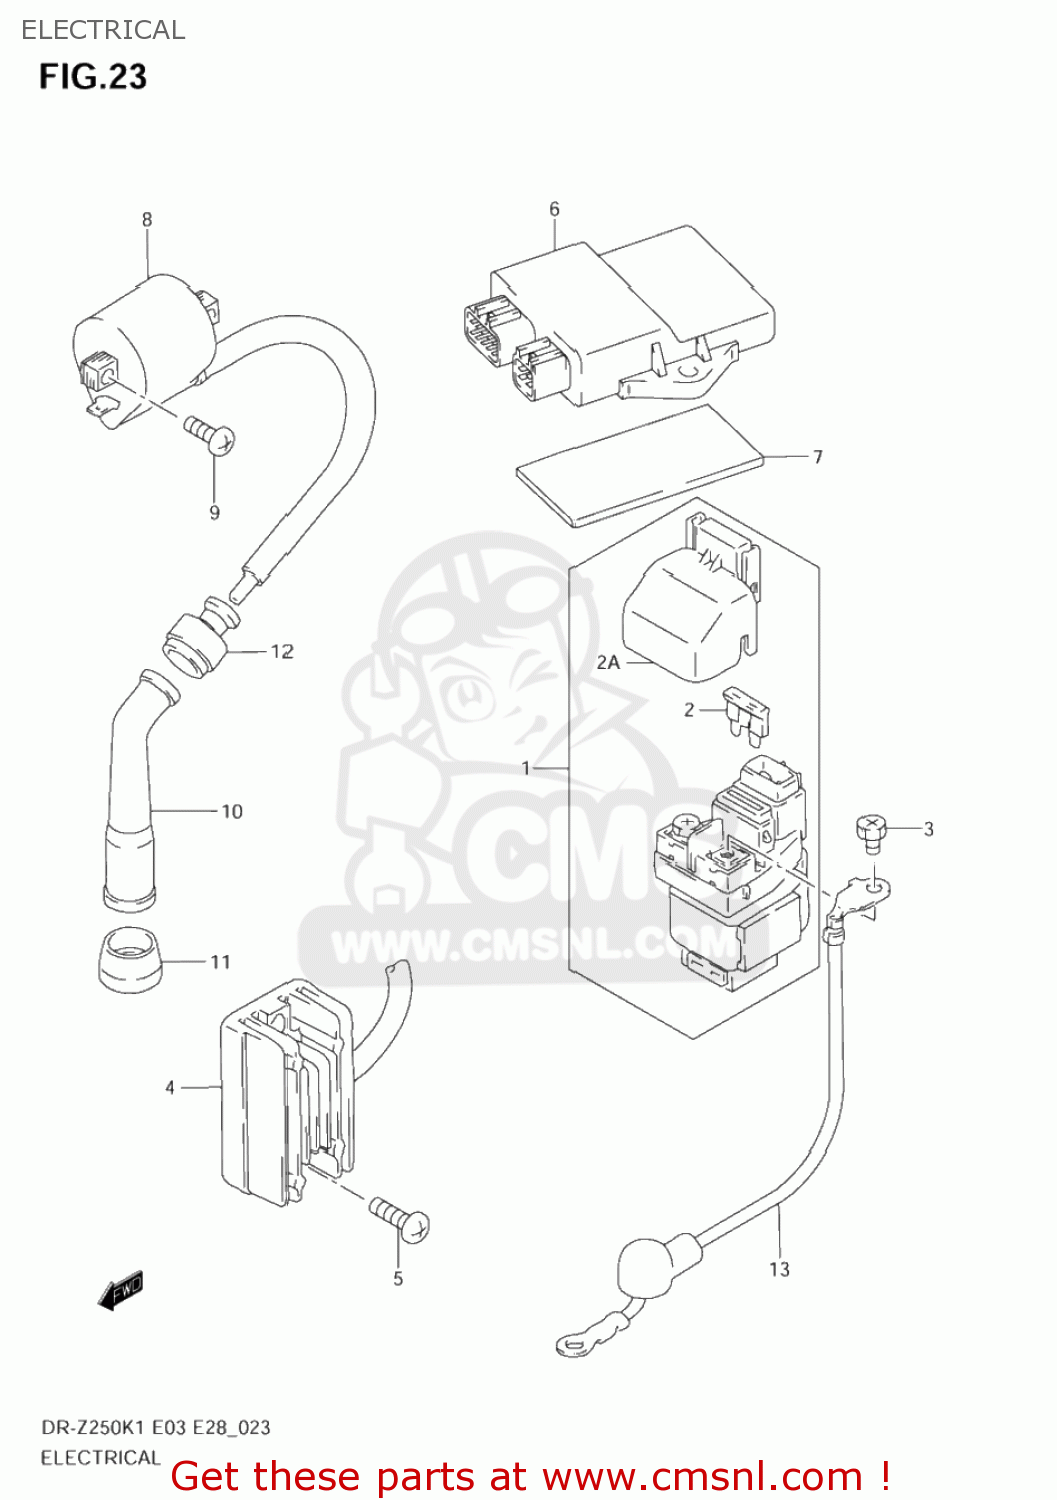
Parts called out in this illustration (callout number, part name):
1	RELAY ASSY,STARTING MOTOR
2	FUSE(10A)
2A	COVER
3	SCREW(6X8)
4	RECTIFIER ASSY
5	BOLT
6	CDI UNIT
7	PROTECTOR(170X95X3.0)
8	COIL ASSY,IGNITION
9	SCREW 6X16
10	CAP ASSY,SPARK PLUG
11	SEAL,SPARK PLUG
12	SEAL,HIGH TENSION CORD
13	WIRE,STARTER MOTOR
